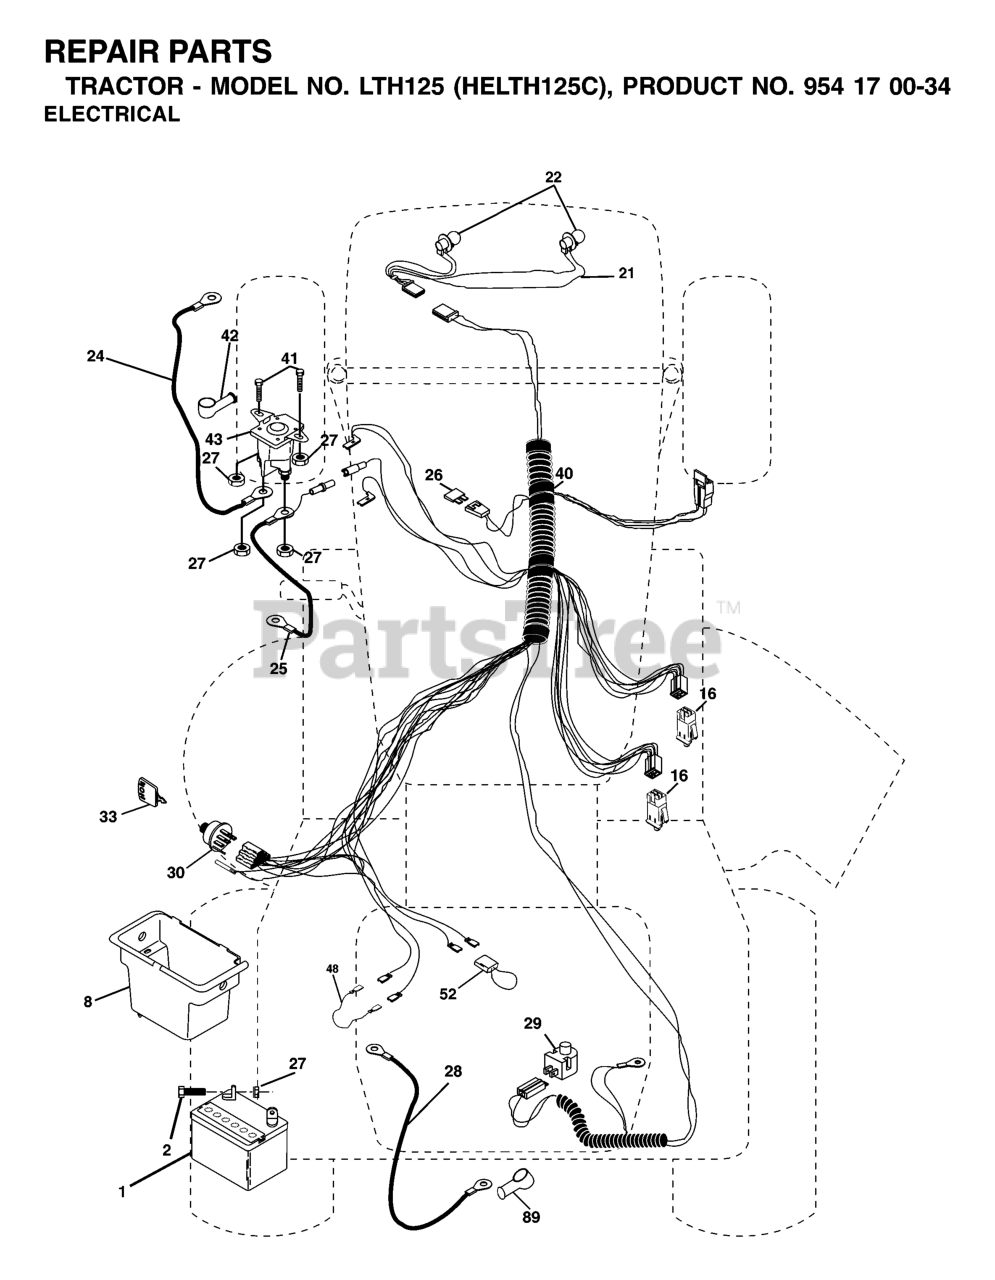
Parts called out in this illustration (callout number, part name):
1	Battery 12 Volt 25 Amp
2	BOLT.HEX.1/4.X.3/4.DICHROMATE
8	BOX.BATTERY.FENDER
16	SWITCH INTERLOOK PUSH-IN
21	HARNESS.W/LIGHT SOCKET
24	BATTERY CABLE GT
25	CABLE BATTERY
26	FUSE 20AMP
27	NUT
28	CABLE T
29	RP.SWITCH.PLUNGER.NC.GRAY
30	IGNITION SWITCH
33	KEY MLD GEN DELTA
40	HARNESS.IGNITION
41	BOLT
42	TERMINAL COVER
43	SOLENOID
48	ADAPTER.AMMETER
52	WIRE PROTECTION LOOP
89	COVER TERMINAL
